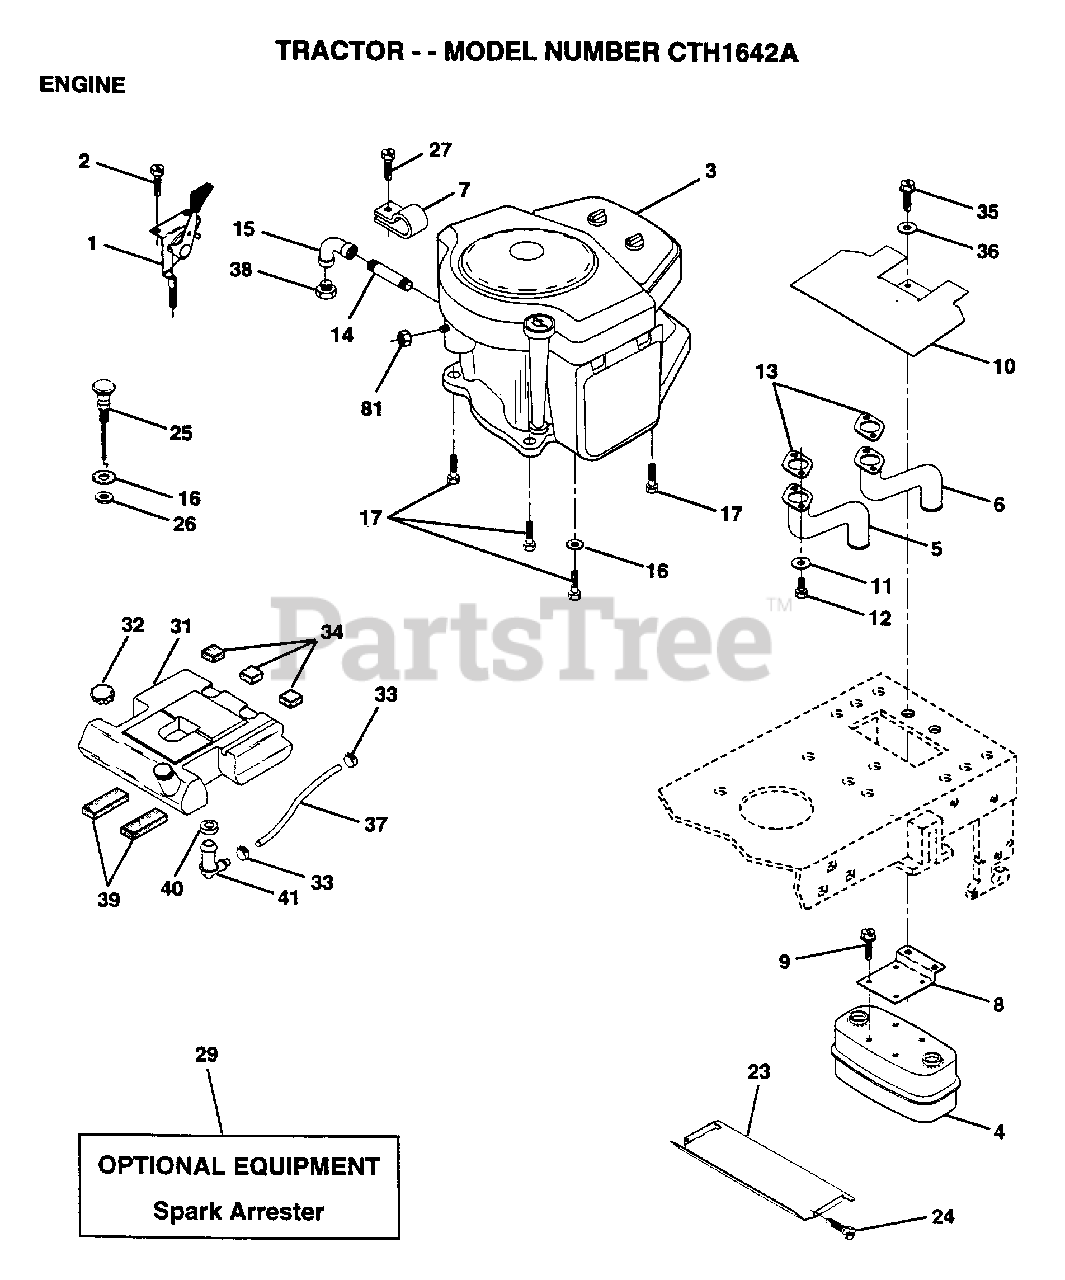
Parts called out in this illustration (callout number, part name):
2	SCREW LT
3	ENGINE, B&S
5	EXHAUST.B&S.18.LH
6	EXHAUST.B&S.18.RH
7	CLAMP.TUBE.DBL.EN
8	BRACKET MUFFLER
9	SCREW ST
10	SHIELD.HEAT.
11	LOCKWASHER
14	PIPE NIPPLE LT
15	ELBOW
16	LOCKWASHER
17	SCREW LT
23	HEAT SHIELD
24	SCREW
25	"CONTROL.CHOKE.51"""
27	SCREW.10-24X1/2
32	CAP ASM FUEL
33	HOSE CLAMP
34	PAD-SPACER LT
35	SCREW
36	WASHER
37	FUEL LINE T
39	PAD IDLER TI
40	BUSHING OUTLET T
41	STEM.TANK.FUEL
81	NUT
